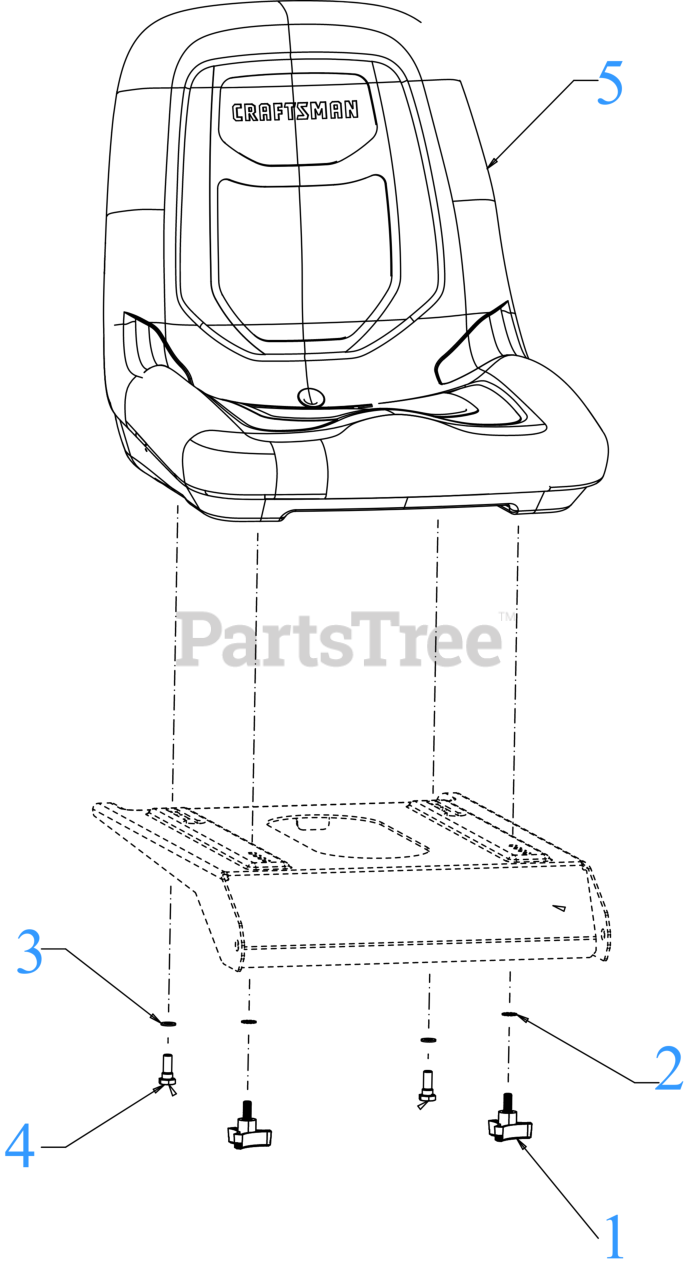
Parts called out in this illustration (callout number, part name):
1	3 PRONG KNOB 5/16-18
2	WASHER
3	FLAT WASHER ID-.320 x .598
4	SHOULDER SCREW .437
5	18" SEAT (4 PT MTG)
